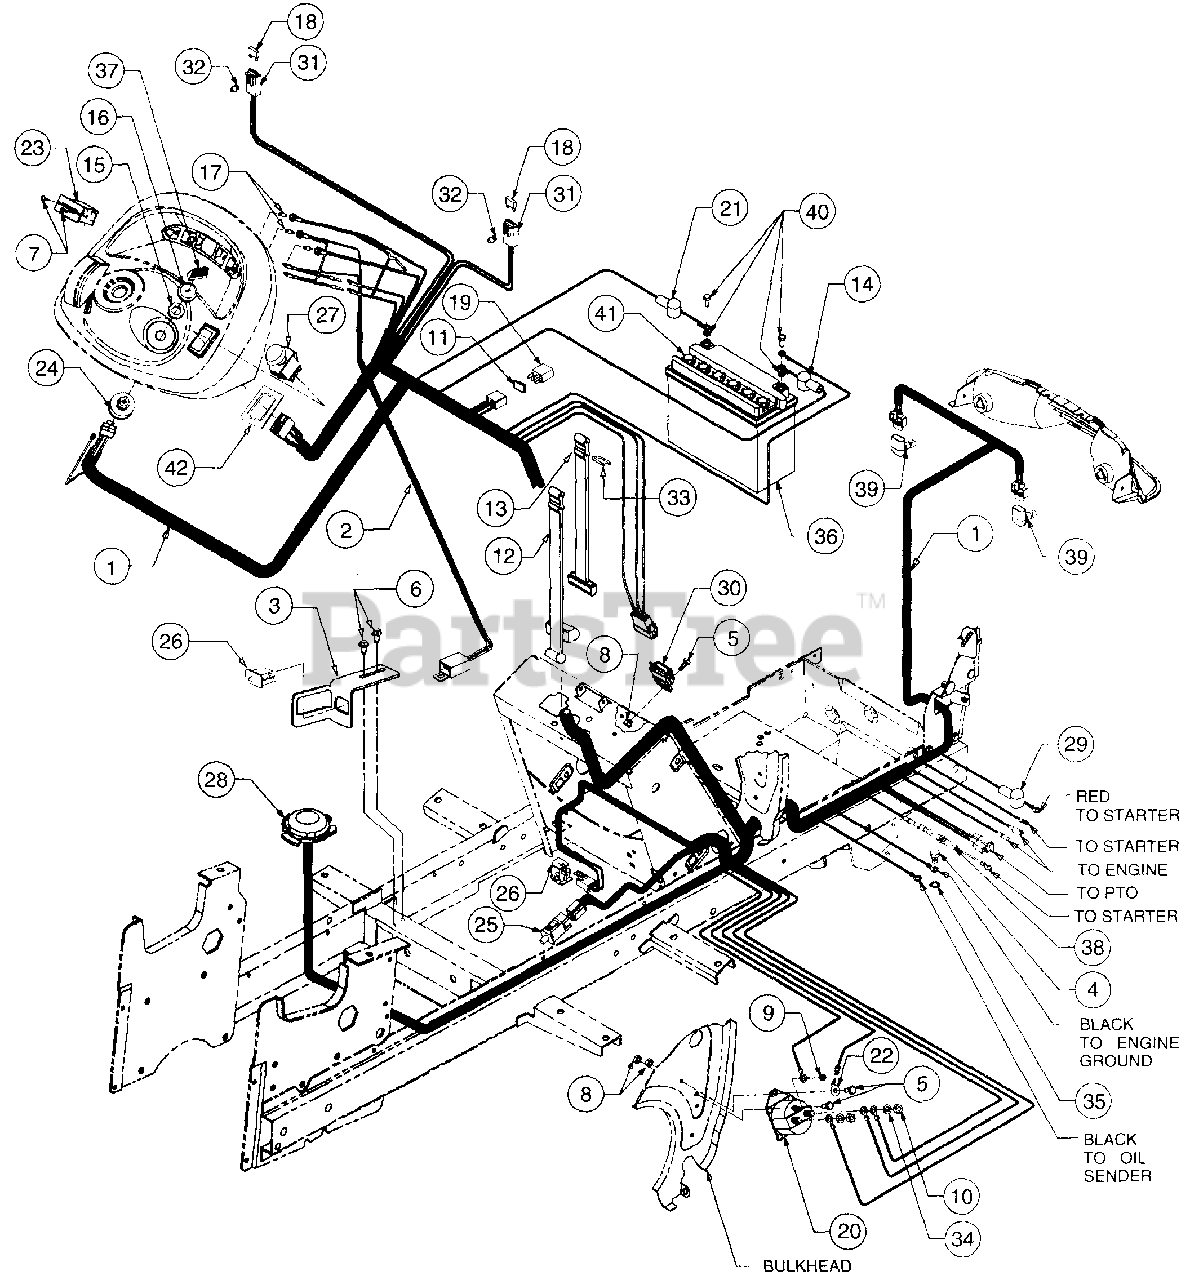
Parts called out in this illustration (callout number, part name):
1	Wire Harness, Main
2	Wire Harness, Indicator Light
3	Bracket, Clutch Switch
4	Screw, Hex Cap, 3/8-16 x .50
5	Screw, Hex Cap, 1/4-20 x .625
6	Screw, Hex Wash Hd Tapp, 1/4-20 x .5
7	Screw, Truss Hd Tapp, #6 x .62
8	Nut, Hex Sems, 1/4-20
9	Nut, Hex, #10-32
10	Nut, Hex, 5/16-18 GR5
11	Gasket, Silicone
12	Strap, Battery Retainer
13	Strap, Battery Retainer
14	Cover, Terminal Black
15	Nut, Ignition Switch
16	Cap, Ignition Switch
17	Bulb, Indicator
18	Fuse, 25 Amp
19	Relay
20	Solenoid, Starter
21	Cover, Terminal Red
22	Lug, Quick Connect
23	Hour Meter
24	Switch, Ignition
25	Switch, Interlock
26	Switch, Snap Mount - Normally Closed
27	Switch, PTO
28	Switch, Seat
30	Module, Voltage Sensor
31	Holder, Fuse
32	Clip, Fuse Holder Mounting
33	Hook, Wire Rectangular
34	Washer, Lock, 5/16
35	Washer, External Lock, 3/8
36	Battery
37	Key, Ignition
38	Diode Assembly w/Lead
39	Bulb, Head Lamp
40	Battery Cable Hardware
41	Cap, Battery
42	Bracket, PTO Switch Retainer
